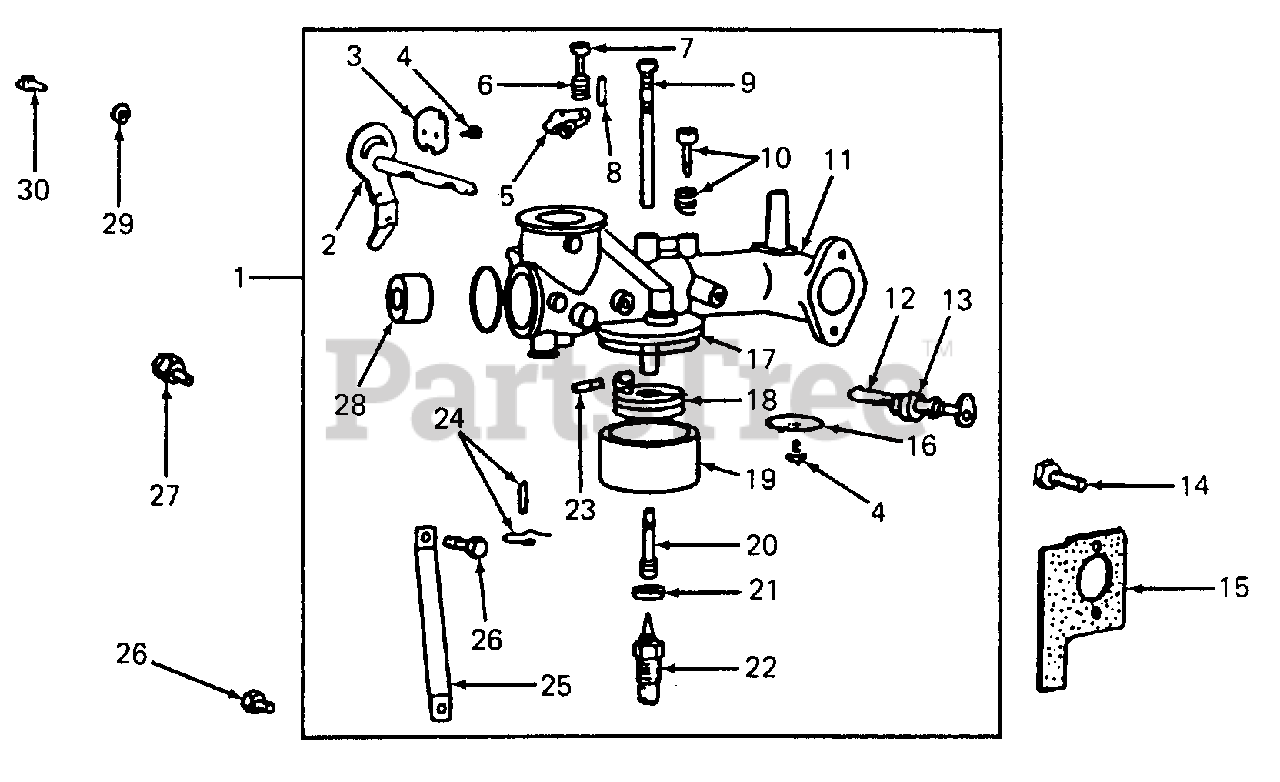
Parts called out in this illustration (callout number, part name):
1	Carburetor Assembly
2	Shaft & Lever, Manual Choke
3	Valve, Choke
4	Screw, Throttle & Choke Valve Mtg. Stem
5	Stop, Throttle
6	Spring, Throttle Adjustment
7	Screw, Machine Fill Hd 8/32 X 5/8 in.
8	Pin, Throttle Stop
9	Nozzle, Carburetor
10	Valve Assy, Carburetor Idle
11	Body Assy, Carburetor
12	Shaft & Lever, Throttle
13	Seal, Throttle Shaft
14	Screw, Carburetor Mtg
15	Gasket, Carburetor Mtg
16	Valve, Throttle
17	Gasket, Float Bowl
18	Float, Carburetor
19	Bowl, Float
20	Screw, Nozzle
21	Washer, Float Bowl
22	Valve, Needle
23	Pin, Float Hinge
24	Valve, Fuel Inlet
25	Bracket, Carburetor
28	Venturi, Carburetor
29	Washer, Choke Lever
30	Screw, Choke Lever
